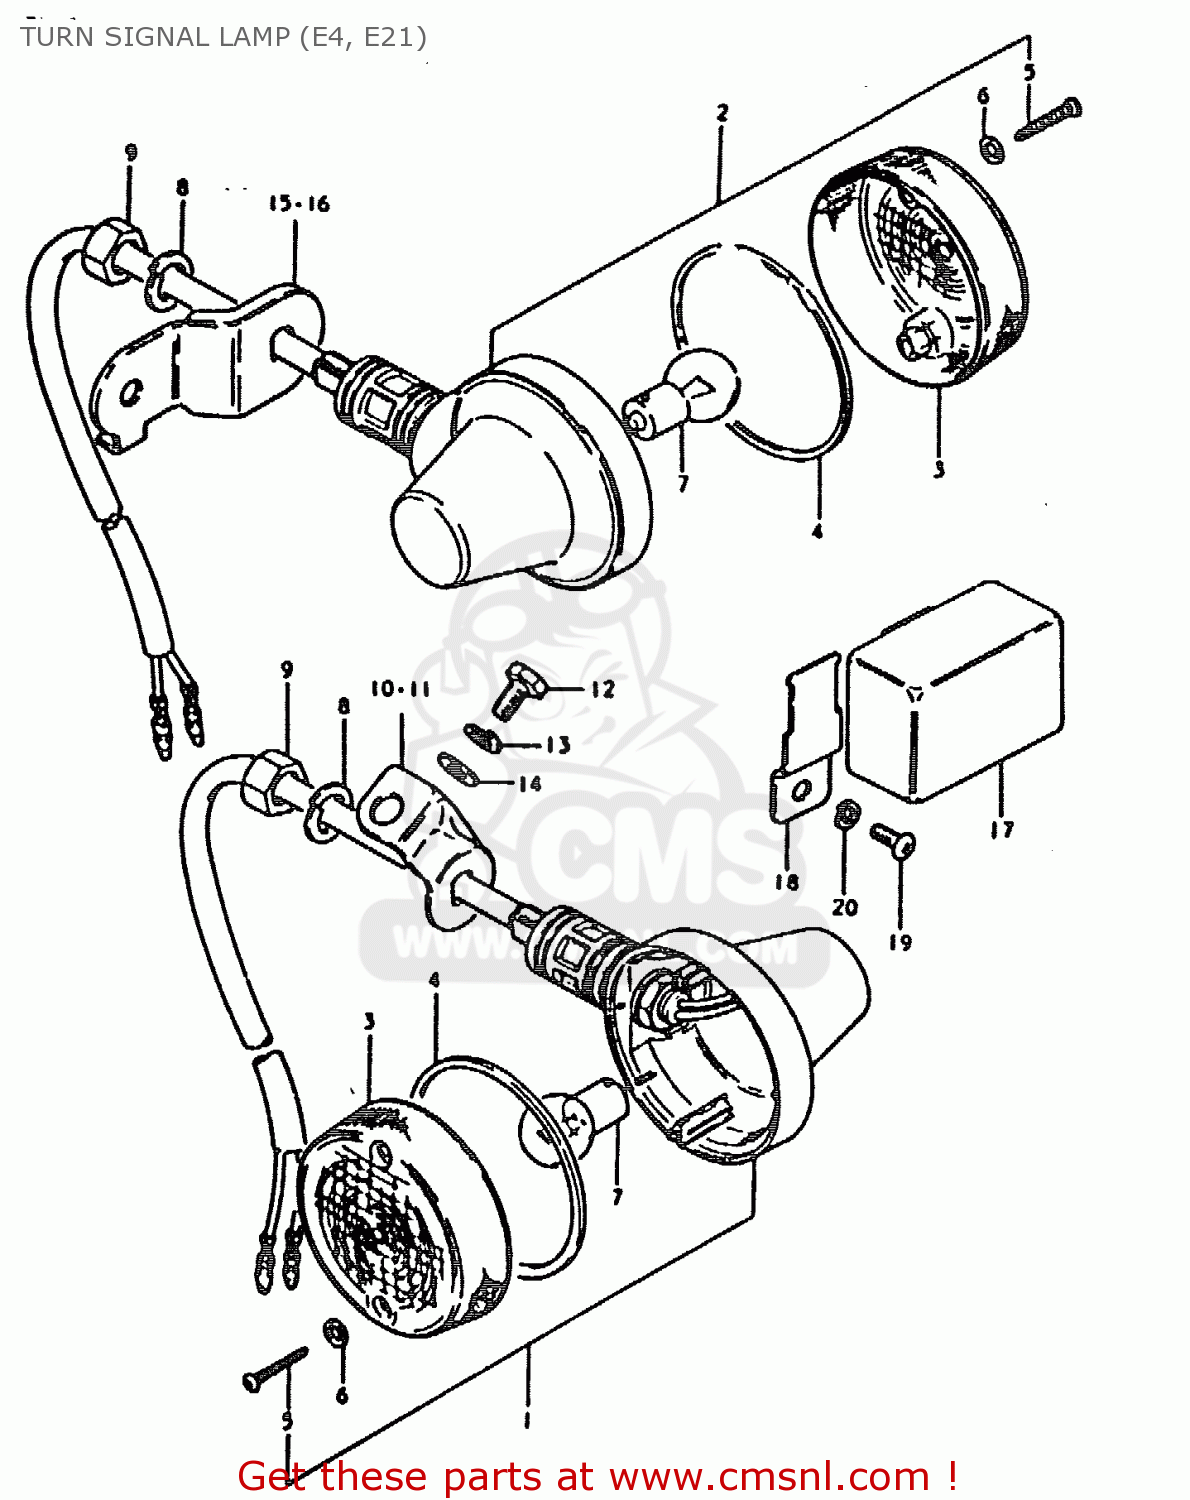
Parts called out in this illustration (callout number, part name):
1	LAMP ASSY,RR TURNSIGNAL
2	LAMP ASSY,RR TURNSIGNAL
3	LENS
4	GASKET (NAS)
5	SCREW TAPP.
6	GASKET (NAS)
7	BULB (6V,21W)
8	WASHER,LOCK 12
9	NUT
10	BRACKET,TURN SIGNAL LAMP
11	BRACKET,TURN SIGNAL LAMP
12	BOLT
13	LOCK WASHER
14	WASHER
15	BRACKET,REAR TURN SIGNAL
16	BRACKET,REAR TURN SIGNAL
17	RELAY, TURN SIGNAL
18	BRACKET,TURN SIGNAL RELAY
19	SCREW 6X12
20	LOCK WASHER
